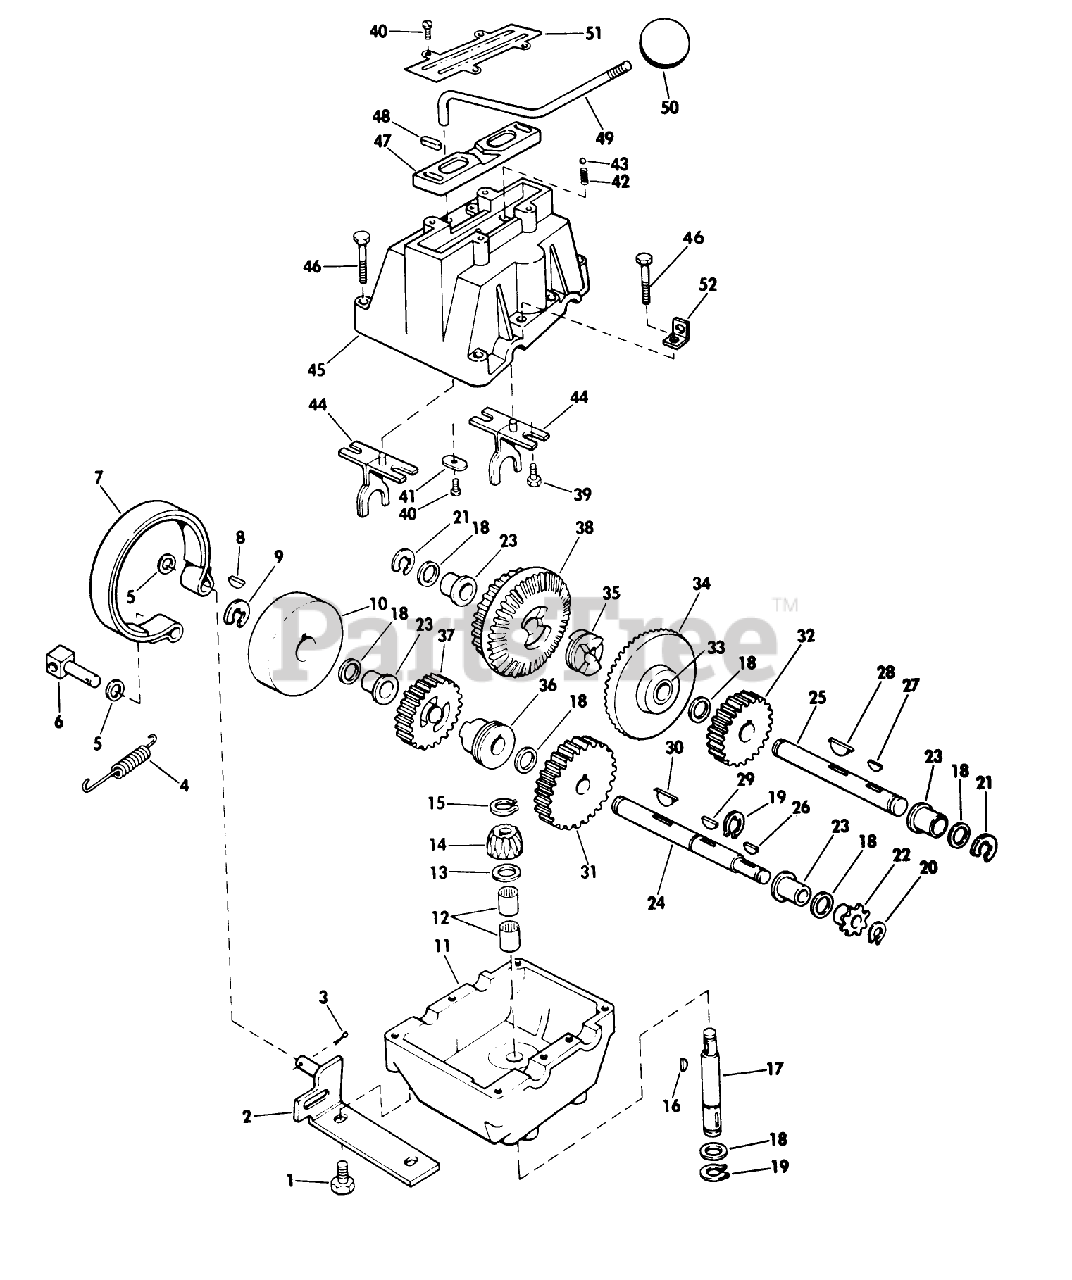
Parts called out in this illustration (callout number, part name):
11	Lower Housing
15	Retaining Ring
18	Washer (.040)
18	Washer (.030)
18	Washer (.050)
19	Retaining Ring
20	Retaining Ring
21	Retaining Ring
22	Sprocket-8 Tooth
24	Output Shaft
25	Drive Shaft
26	Key-Woodruff
27	Key-Woodruff
28	Key
29	Key-Woodruft
30	Key
31	Spur Gear-28 Tooth
32	Spur Gear-22 Tooth
33	Bearing-Sleeve
34	Bevel Gear
35	Clutch Collar
36	Clutch Collar
37	Spur Gear-22 Tooth
38	Gear-Spur and Bevel
39	Screw Shoulder
40	Screw
41	Detent-Cover Plate
42	Spring-Detent
43	Ball-Detent
44	Shifter Fork
45	Housing-Upper
46	Bolt
47	Cam Plate
48	Nylon Slide
49	Shift Lever
50	Shifter Knob
51	Top Cover Plate
52	Bracket
